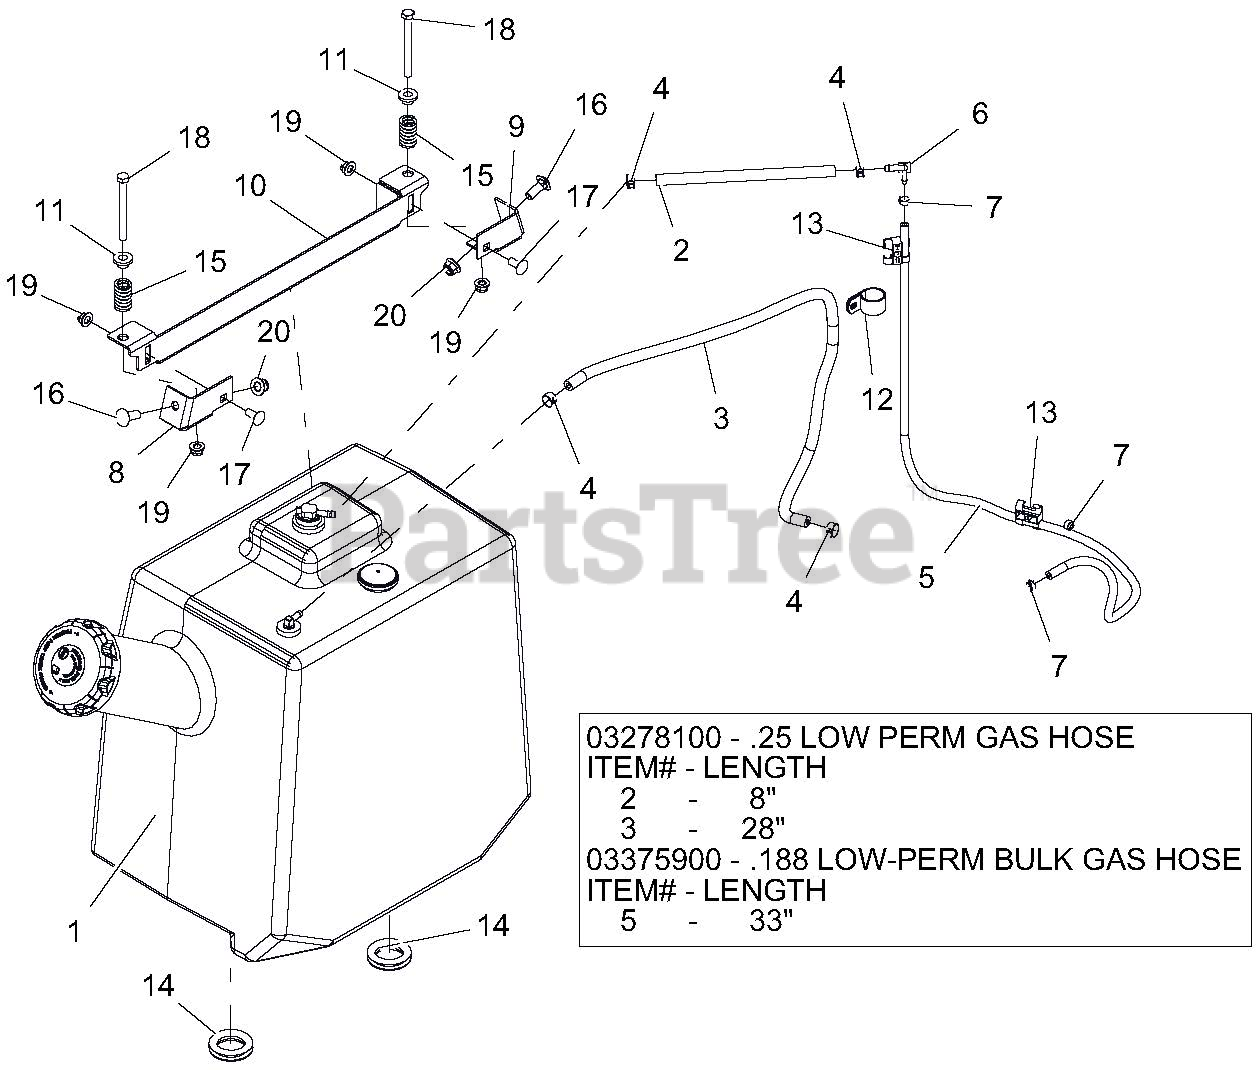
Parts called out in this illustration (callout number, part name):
1	ASSY, EPA PROSTANCE FUEL TANK
2	.25 LOW PERM GAS HOSE
3	.25 LOW PERM GAS HOSE
4	CLAMP, FUEL LINE
5	HOSE, .188 LOW-PERM BULK GAS
6	FITTING-3/16X1/4 90DEGREE VAC
7	CLAMP - HOSE, SPRING .188
8	WLDMT, TANK HOLDDOWN-RH
9	WLDMT, TANK HOLDDOWN-LH
10	HOLDDOWN, FUEL TANK
11	BSHG, FLG .385 X .500 X .875 X .406
12	CLAMP, CUSHIONED STEEL REV
13	CLIP, T, .38-.50
14	GROMMET, 1.25"
15	SPRG, COMPRESSION
16	BLT-RDHDSQNK .38-16X1.00 G5 YWZC
17	BLT-RDHDSQNK .31-18X.75 G5 YWZC
18	BLT-HEX .31-18X3.25 GR5 YWZC
19	NUT-LK-NYL-FLG .31-18 YWZC
20	NUT-LK-NYL-FLG .38-16 YWZC
